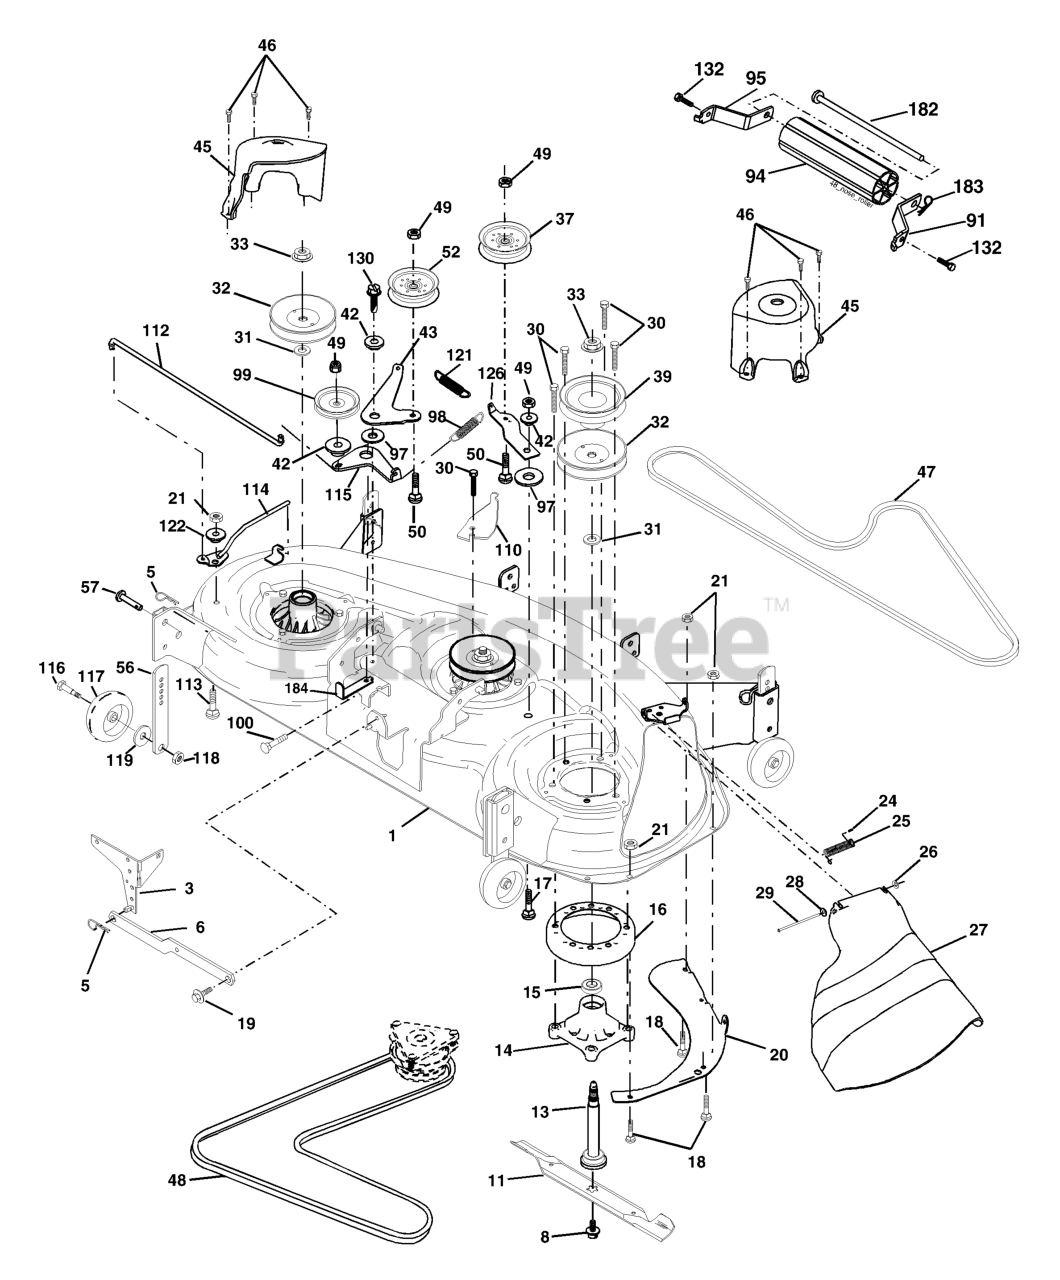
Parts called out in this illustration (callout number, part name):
1	DECK WELDMENT MOWER, 48
3	BRACKET ASM.
5	RETAINER-SPRNG RB
6	BAR SWAY DECK
8	BOLT 7/16 ASM BLADE
11	BLADE.MULCH.48"
11	48" HI-LIFT BLADE
13	SHAFT ASM W/LOWER BEARING
14	HOUSING, MANDREL 48"
16	STRIPPER.MANDREL.ROUND.BLACK
17	BOLT
18	BOLT
19	BOLT SHD 5/16-18
20	BAFFLE, VORTEX MWR
21	LOCKNUT
24	CAP-SLEEVE LT
25	SPRING, TORSION
26	NUT PUSH M
27	DEFLECTOR SUBS TO 532 180655
28	Washer 11/32 x 5/8 x 16 Ga.
29	ROD.HINGE
30	SCREW, WASHER HEAD
31	WASHER.SPACER.MANDREL
32	PULLEY MANDREL
33	NUT, FLG TOPLOCK 9/16"
37	PULLEY.IDLER.FLAT
39	PULLEY.DRIVEN.DECK.48'
42	SPACER RETAINER
43	ARM, IDLER SECONDARY
45	COVER.MANDREL.DECK.48"
46	SCREW.1/4-20X5/8
47	V-BELT, 48"SECONDARY
48	V-BELT PRIMARY 48"
49	NUT LOCK FLG 3/8-16 UNC
50	BOLT.3/8-16X1.50
52	PULLEY.IDLER.FLAT.46.PR.DR.
56	BAR.ADJUST.WHEEL.ANTI.SCALP.BL
57	RIVET.PIN.HEAD.YELLOW.
91	BRKT.NOSEROLLER.RH.48"
94	NOSE ROLLER 48"
95	BRKT.NOSEROLLER.LH.48"
98	SPRING PRIMARY DRIVE
99	IDLER PULLEY
100	BOLT
110	ARM, SPRING SECONDARY
112	LEVER, TENSION RELIEF LINK
113	BOLT.CARR.SQNK.5/16-18UNC.X3/4
114	LEVER ASM, TENSION RELIEF
115	ARM, SPRING TENSION RELIEF
116	SHOULDER BOLT
117	WHEEL GAGE DONUT
118	LOCKNUT
119	WASHER.5/16.FLAT.STE.STD.
121	SPRING.DRIVE.SECONDARY.48".DEC
122	BUSHING, PIVOT TENSION RELIEF
126	ARM, IDLER PRIMARY DECK
130	SCREW 3/8-16X1
132	SCREW, 3/8-16X3/4
182	ROD.ROLLER.NOSE.NARROW.48"
183	SPRING RETAINER
184	KEEPER BELT IDLER PLATED
